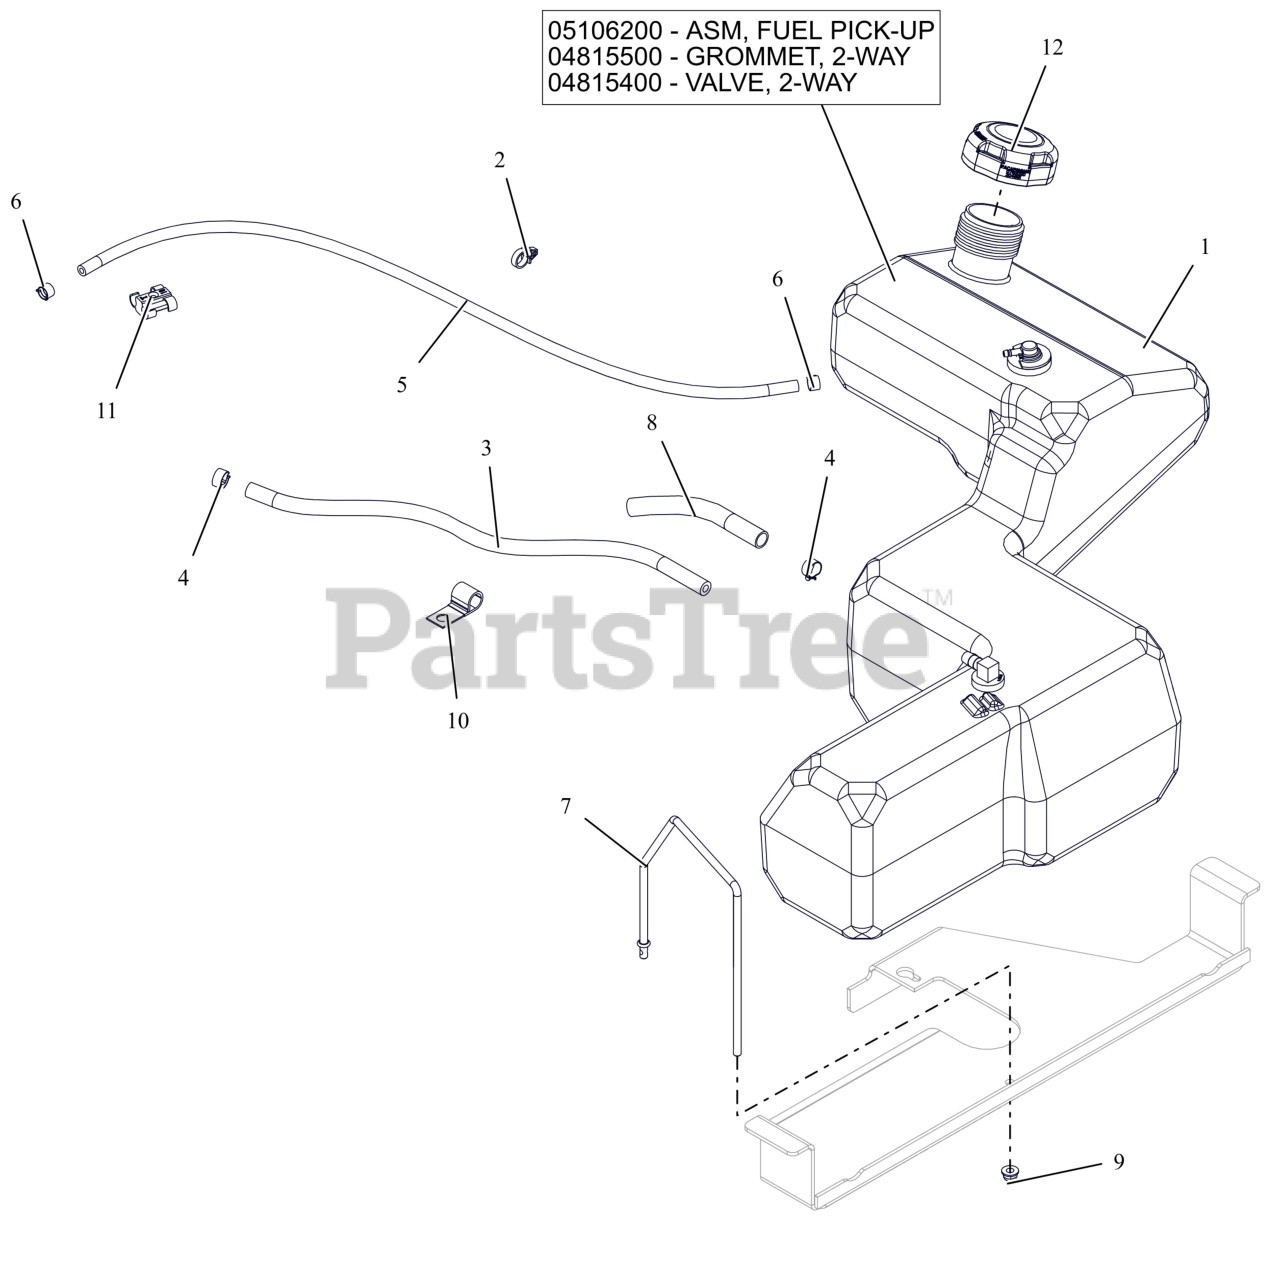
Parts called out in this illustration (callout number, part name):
1	ASM, FUEL TANK-IKON
1	ASM, IKON FUEL PICK-UP
1	GROMMET, 2-WAY
1	VALVE, 2-WAY
2	ROUTING CLIP (1/2" ID)
3	HOSE, .25 LOW-PERM BULK GAS
4	CLAMP, FUEL LINE
5	HOSE, .188 LOW-PERM BULK GAS
6	CLAMP-HOSE, SPRING .188
7	BRKT, FUEL TANK HOLD DOWN
8	WRAP, ANTIABRASION .5X.064WALL
9	NUT,NYL-FLG .25-20 GF ZCC
10	J-CLAMP
11	CLIP, T, .38-.50
12	CAP, FUEL - 2.25 RATCHET INLET VENT
